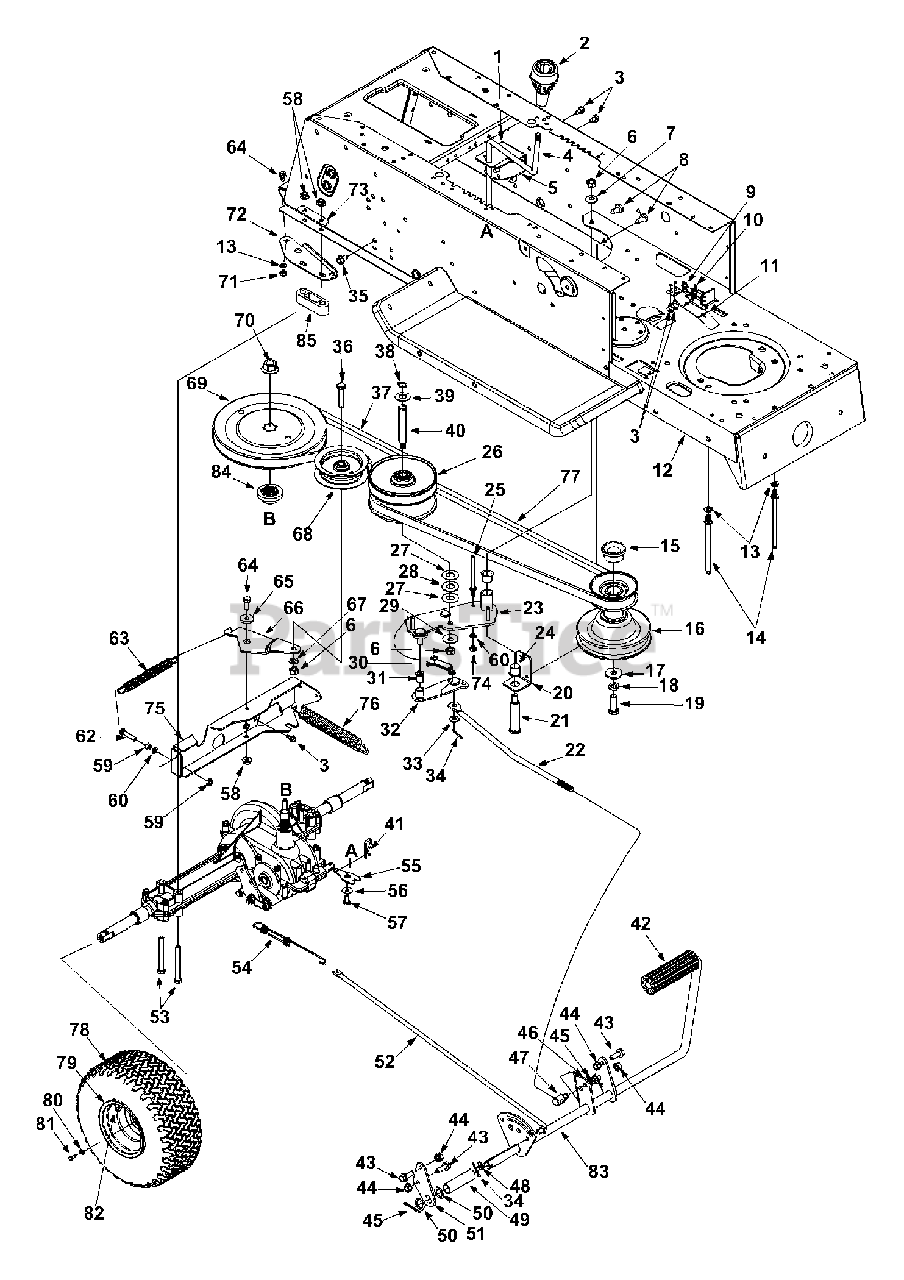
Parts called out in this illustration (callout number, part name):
2	Shift Knob
3	Self Tap. Screw 1/4-20 x .50" Lg.
4	Shift Lever Assembly
5	Comp. Spring-Clip
6	Hex Nut 3/8-24 Thd.
7	Bell Wash. .375" I.D.
8	AB-Tap Scr. 5/16-18 x .75" Lg.
9	AB-Tap Scr. #10-16 x .5" Lg.
10	Switch Plate
11	Switch Spring Actuator
13	L-Wash. 5/16" I.D.
14	Belt Guard Pin 4.75" Lg.
15	Spacer 1" I.D. x 1.25" Lg.
16	Engine Pulley
17	Fl. Wash. .450" I.D.
18	L-Wash. 7/16" I.D.
19	Hx Hd. Cap Scr. 7/16-20 x 1.25" Lg.
20	Bearing Shaft Bracket Ass'y
21	Shoulder Screw
22	Speed Control Link
25	Belt Keeper 3" Lg.
26	Variable Speed Pulley Ass'y
27	Fl-Wash.
28	Thrust Bearing .56" I.D. x 1.25"
29	Bell Wash. .390" I.D. x 1.13"
30	Extension Spring
31	Flange Bearing
33	Fl-Wash. .344" I.D.
34	Cotter Pin
35	TT-Tap Scr. 5/16-18 x .625" Lg.
36	Hex Hd. Cap Scr. 3/8-24 x 1.75" Lg.
37	V-Belt
38	Snap Ring .56" Dia.
39	Fl-Wash. .570" I.D. x .120" Lg.
40	Shaft .56" Dia. x 3.79" Lg.
41	Internal Cotter Pin
42	Foot Pad
43	TT-Tap Scr. 5/16-18 x .75"
44	Sems Nut 5/16-18
45	Cotter Pin 1/8- 1.25
46	Fl-Wash .385" I.D. x .62" O.D.
47	Ferrule
48	Fl-Wash. .385" I.D. x .62" O.D.
49	Spacer
50	Fl-Wash. .635" I.D. x .930 O.D.
53	Hex Hd. Cap Scr. 5/16-18
54	Ext. Spring
55	Shift Link Assembly
56	Bell Wash. .265 x .75
57	Hex Hd. Cap Screw 1/4-28
58	Flange L-Nut 5/16-18 Thd.
59	Hex Nut 1/4-28 Thd.
60	L-Wash. 1/4" I.D.
62	Hex Hd. Cap Screw 1/4-28
63	Extension Spring
64	Hex Hd. Cap Screw 5/16-18
65	Shoulder Spacer
67	L-Wash. 3/8" I.D.
68	Flat Idler Pulley
69	V Pulley
70	Flange Nut 9/16
71	Hex Nut 5/16-18 Thd.
74	Hex Nut 1/4-20 Thd.
77	V-Belt
80	Bell Wash. .340 I.D. x .872 O.D.
81	Hex Hd. Cap Scr. 5/16-24
82	Air Valve (Service Only)
85	Spacer
